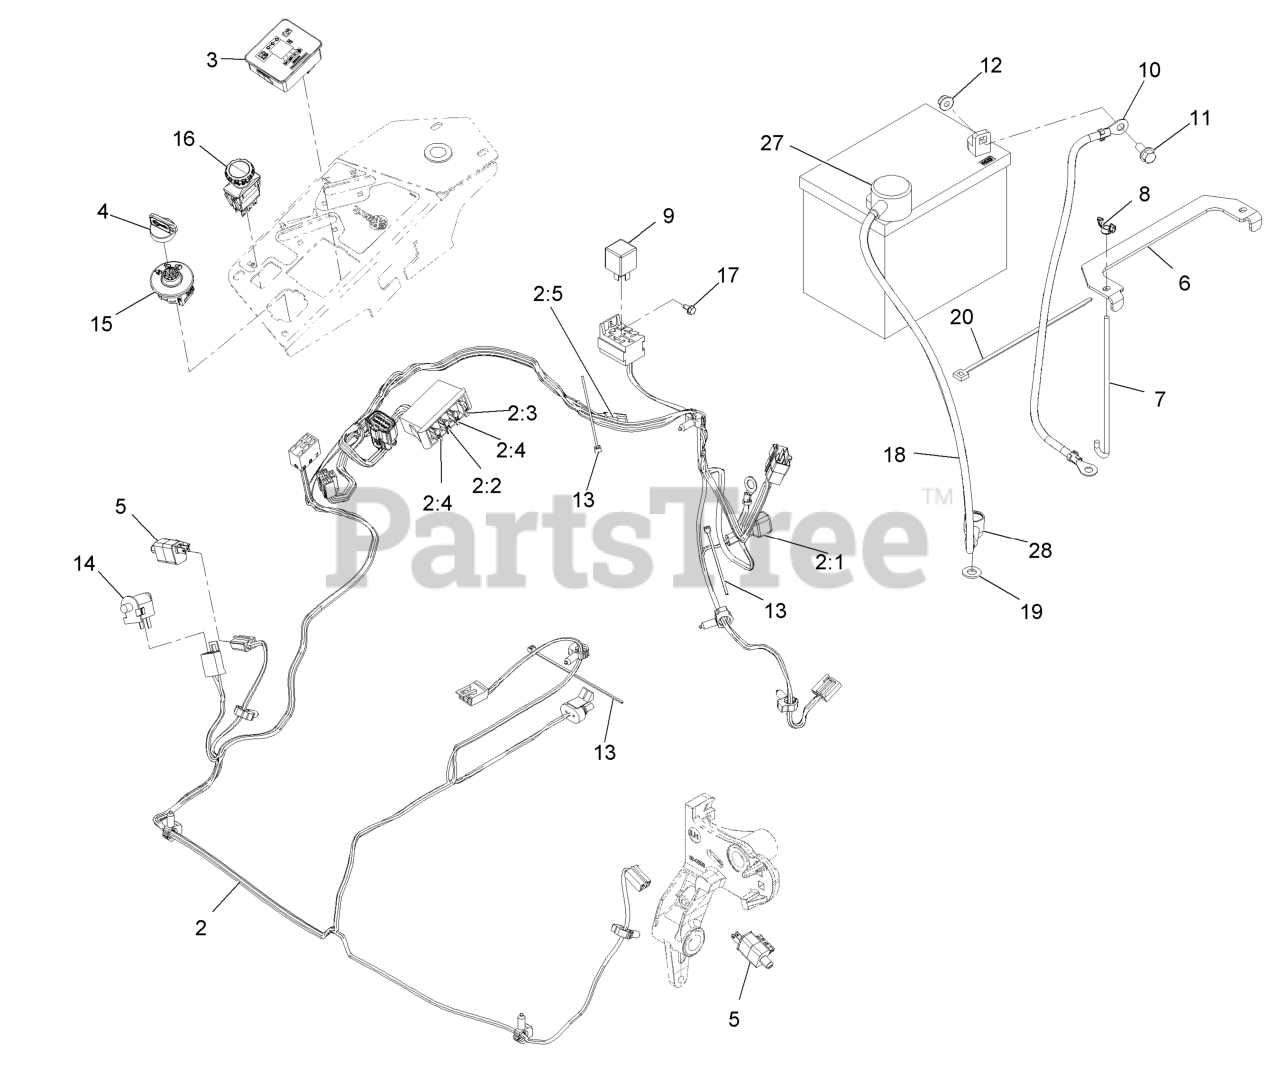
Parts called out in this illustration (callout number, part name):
2	HARNESS-WIRE, MAIN
2:2	FUSE-BLADE, 10 AMP
2:3	FUSE-BLADE, 15 AMP
2:4	FUSE-BLADE, 25 AMP
2:5	CAP-PLUG
3	FUEL/HOUR METER ASM
4	KEY-IGNITION
6	STRAP-TIE DOWN, BATTERY
7	BOLT-HOLDDOWN
8	WINGNUT
10	CABLE-BATTERY, NEGATIVE
11	SCREW-HHF
12	NUT-HF, NI
13	TIE-CABLE
14	SWITCH-BAIL
16	SWITCH-PTO, 10 AMP
17	SCREW-HWH
18	CABLE-BATTERY, POSITIVE
19	WASHER-FLAT
20	TIE-PLASTIC
27	INSULATOR-BATTERY
28	INSULATOR-SOLENOID
